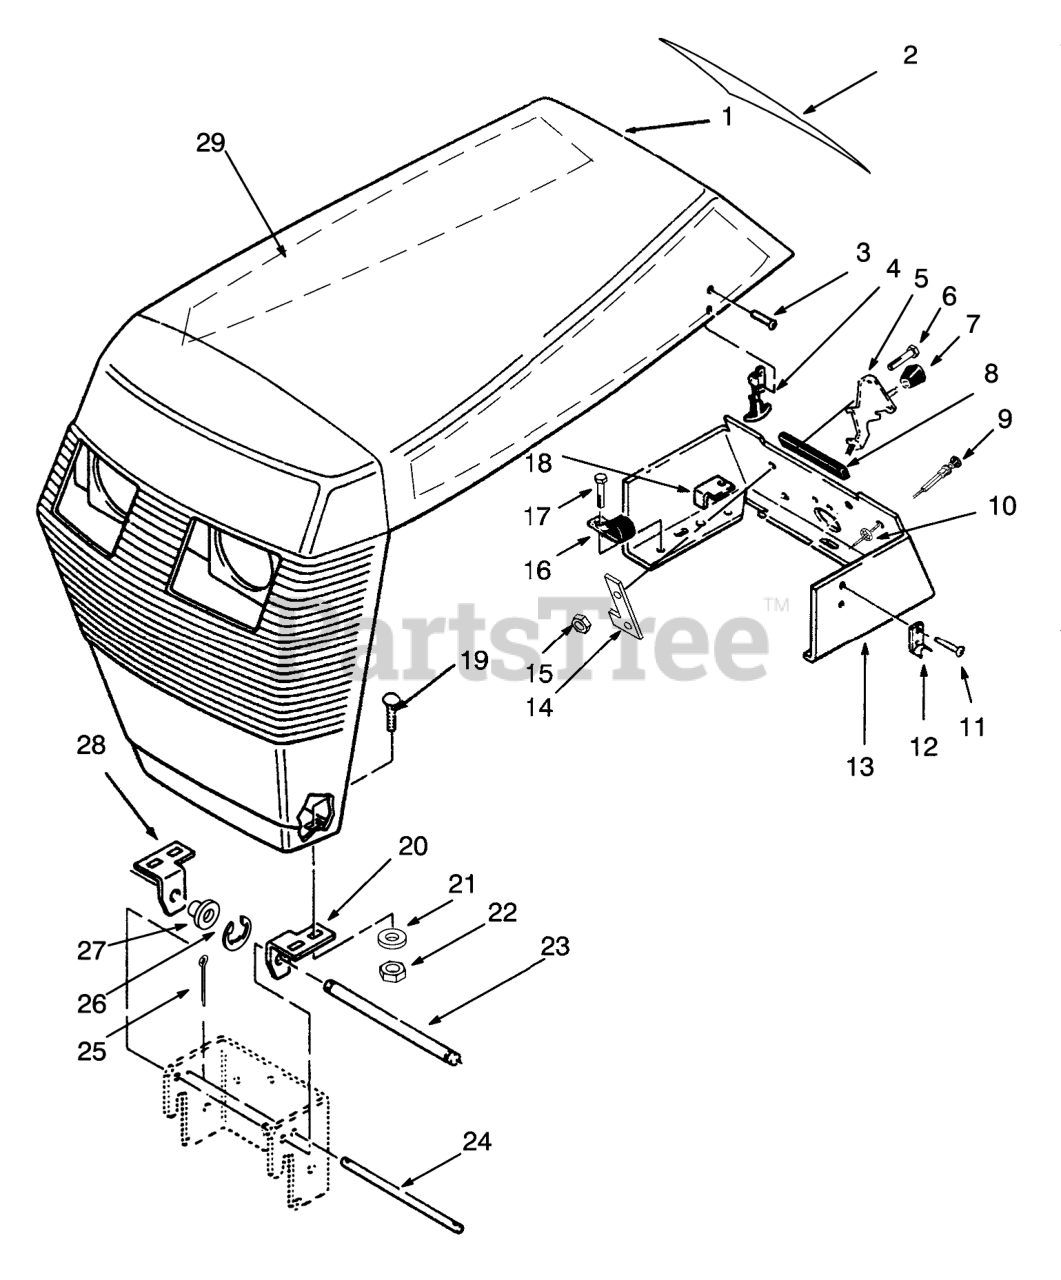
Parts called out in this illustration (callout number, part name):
1	Hood (Incl. Ref. #2)
2	Decal-Danger
3	RIVET-POP
4	HANDLE ASM
5	CONTROL-THROTTLE
6	SCRW-PHC
7	KNOB-CONTROL
8	EDGING-CONSOLE
9	CONTROL-CHOKE
10	NUT-HEX PALNUT
11	POPRIVET 1/8X 1/8 BK
12	KEEPER-LATCH
13	CONSOLE B
14	Washer
15	Nut
16	J-CLIP
17	Bolt
18	STOP-PTO
19	SCREW-CARR
20	BRACKET-GRILL, LH
21	WASHER-FLAT
22	NUT-LOCK
23	ROD-GRILL PIVOT
24	ROD-HOOD STOP
25	Pin-Cotter
26	RING-RETAINING
27	BUSHING-NYLINER
28	BRACKET-GRILL, R H
29	DECAL-HOOD CLASSIC
